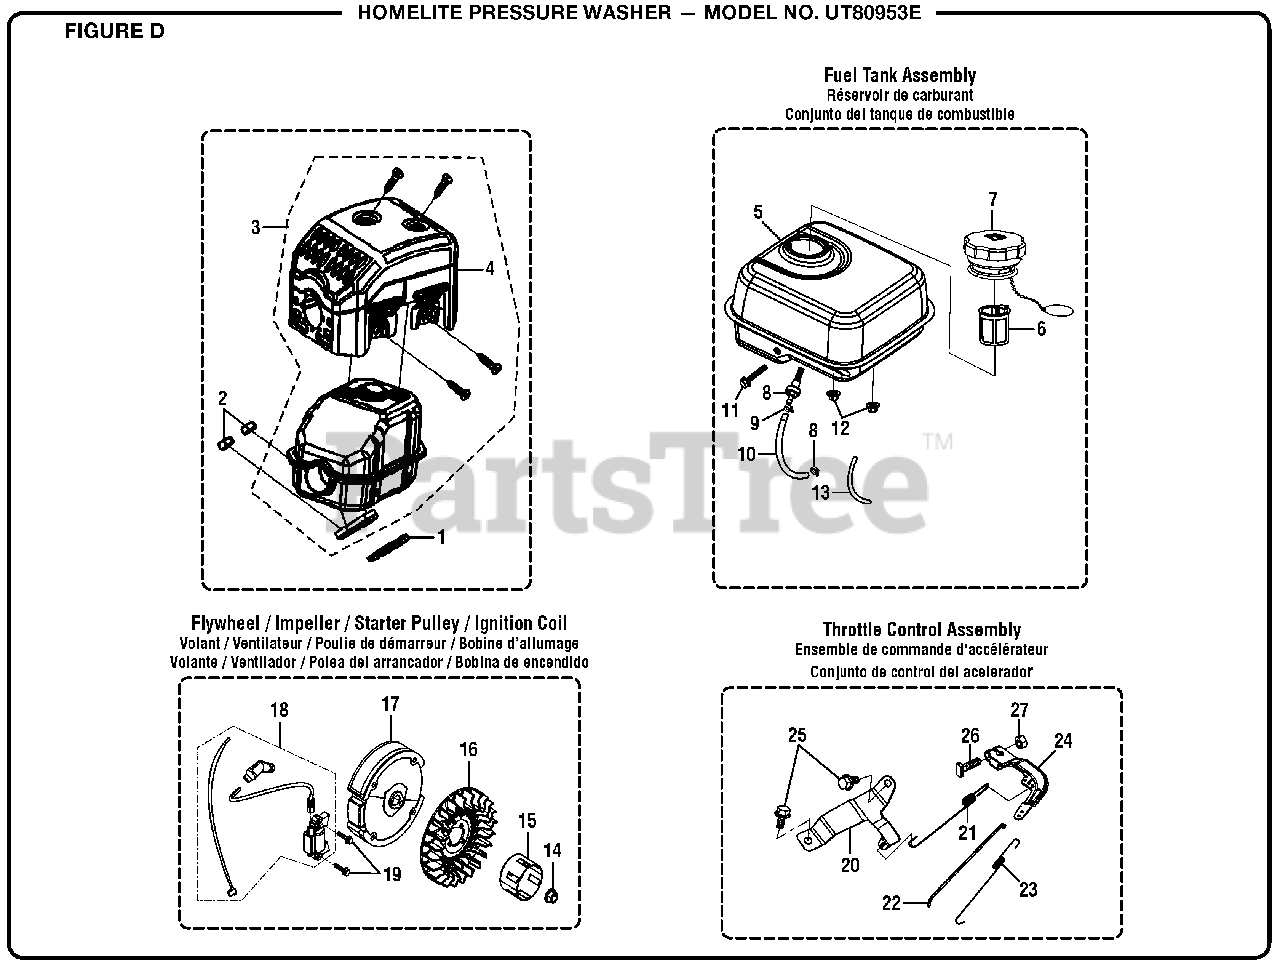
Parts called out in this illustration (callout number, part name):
1	Exhaust Outlet Gasket
3	Muffler Assembly
8	Fuel Filter Assembly
17	Flywheel Assembly
20	Throttle Control Assembly
21	Governor Spring
23	Throttle Valve Return Spring
24	Governor Support Assembly
26	Governor Support Bolt
